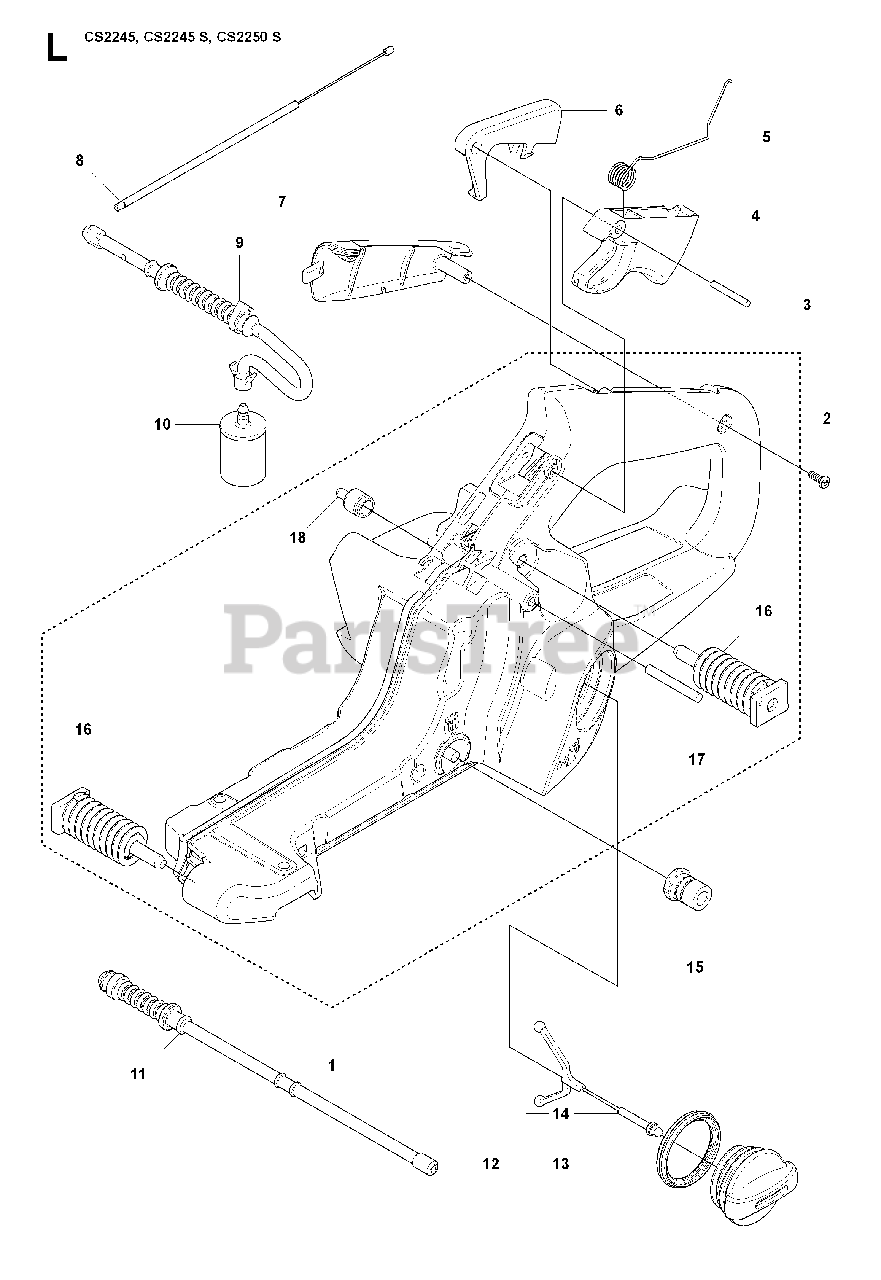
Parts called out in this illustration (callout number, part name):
1	RP FUEL TANK ASSY
4	THROTTLE TRIGGER
6	THROTTLE LOCKOUT
7	HANDLE INSERT
8	THROTTLE WIRE
9	RP FUEL HOSE
10	FUEL FILTER
11	RP RETURN HOSE
12	TANK CAP ASSY
13	SEALING
15	LATERAL SUPPORT
16	ANTI VIBRATIONS ELEMENT
17	GROOVED PIN
18	FUEL TANK VENT
